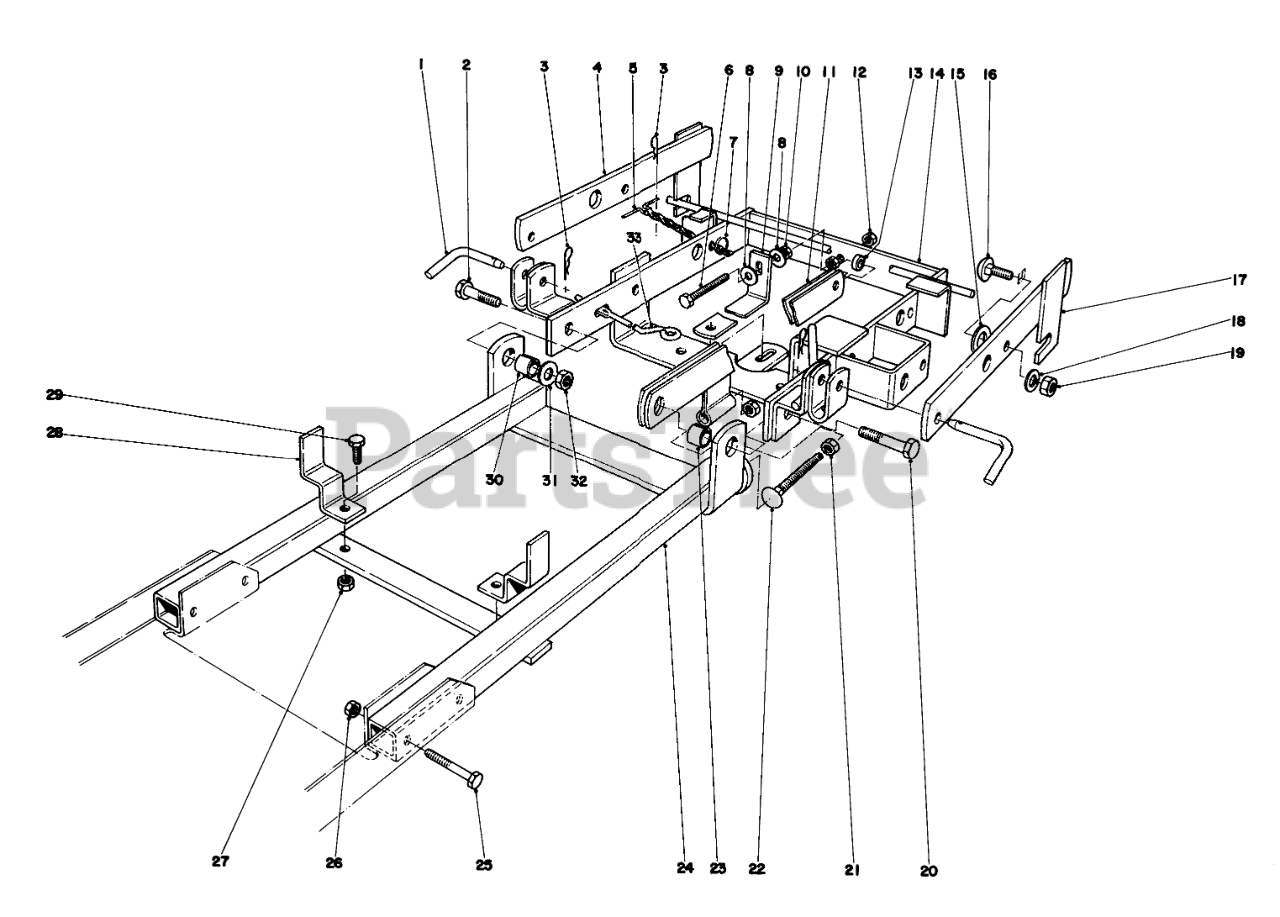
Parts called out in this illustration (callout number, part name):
1	Pin-Roller, Locating
2	SCREW-HH
3	TINNERMAN NUT
4	MountingBracket-R.H.
5	Chain & Toggle
6	SCREW-HH
7	Spring Clip
8	WASHER-FLAT
9	Bracket-Belt Adjust
10	NUT-JAM
11	Lift Extension
12	NUT-HEX
13	Spacer
14	Mounting Frame-Upper
15	Washer-Flat
16	Carriage Bolt
17	Mounting Bracket-L.H.
18	WASHER-LOCK
19	NUT-HEX
20	SCREW-HH
21	NUT-JAM
22	Carriage Bolt
23	Spacer-Bearing
24	Mounting Frame
25	SCREW-HH
26	NUT-LOCK, CONE
27	NUT-LOCK, CONE
28	Stop-Position
29	SCREW-HH
30	Spacer-Idler Pulley
31	WASHER-FLAT
32	1/2-13 CONELOCK NUT
33	Wire-Belt Guide
